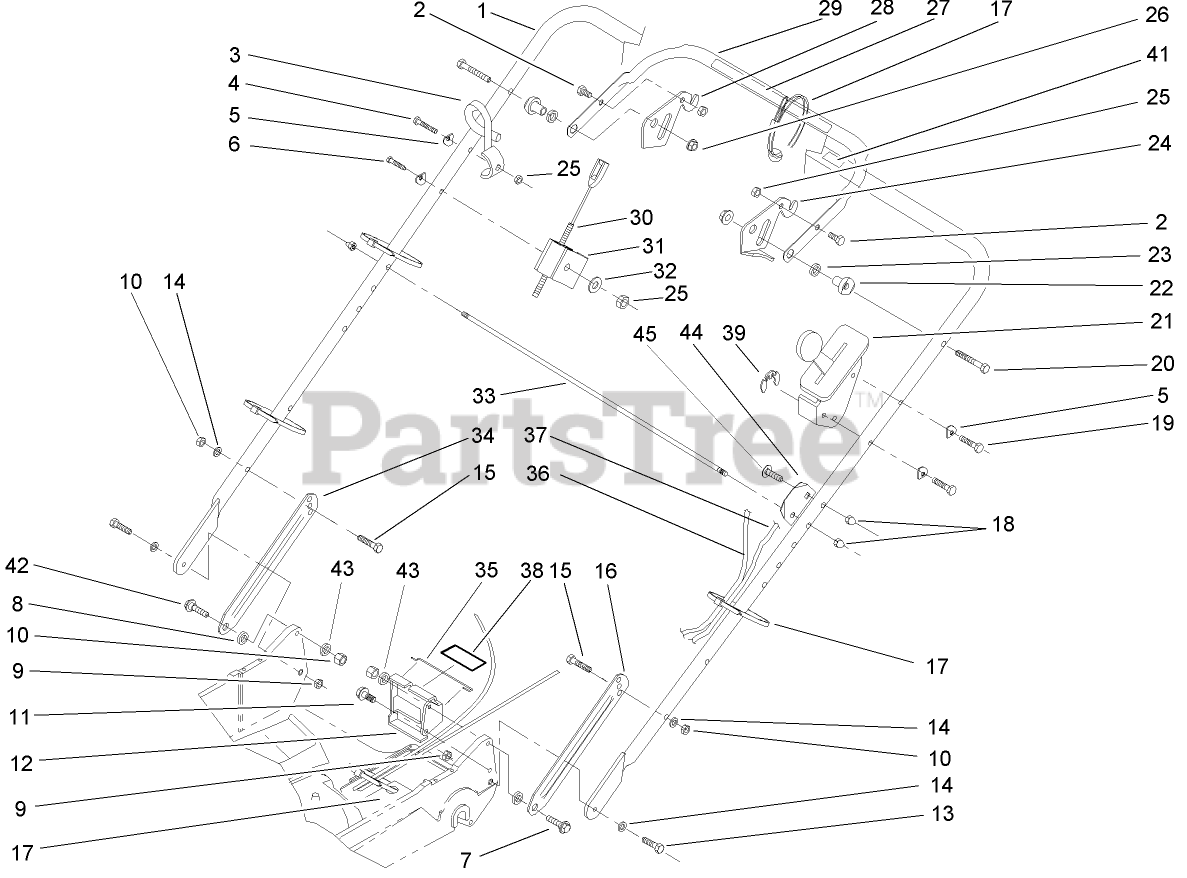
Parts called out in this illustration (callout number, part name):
2	SCREW-HH
3	GUIDE-ROPE
4	SCREW-HH
5	WASHER
6	SCREW-HH
7	SCREW-SHOULDER
8	SPACER
9	NUT-LOCK, NI
10	NUT-LOCK, NI
11	SCREW-HWHTF
12	BRACKET-ADJUSTMENT, TRACTION
13	SCREW-HH
14	WASHER-BELLEVILLE
15	SCREW-HH
16	LATCH-HANDLE, LH
17	TIE-CABLE
18	NUT-CAP
19	SCREW-HH
20	SCREW-HH
22	SPACER-SUPPORT
23	SPACER-NYLON
24	LEVER-CONTROL
25	NUT-LOCK, NI
26	NUT-LOCK, NI
27	DECAL-TRACTION
28	LEVER-CONTROL
29	BAR-CONTROL
30	CABLE-BRAKE
31	SUPPORT-CABLE
32	WASHER-FLAT
33	ROD-SUPPORT, BAG
34	LATCH-HANDLE, RH
35	RETAINER-CABLE
36	CABLE-TRACTION
37	THROTTLE CABLE ASM
38	DECAL-POSITION, GEAR
39	E-RING
41	DECAL-PROTECTION, EAR
42	SCREW-SHOULDER
43	WASHER-PLAIN
44	PLATE-ALIGNING, BAG
45	SCREW-CARR
